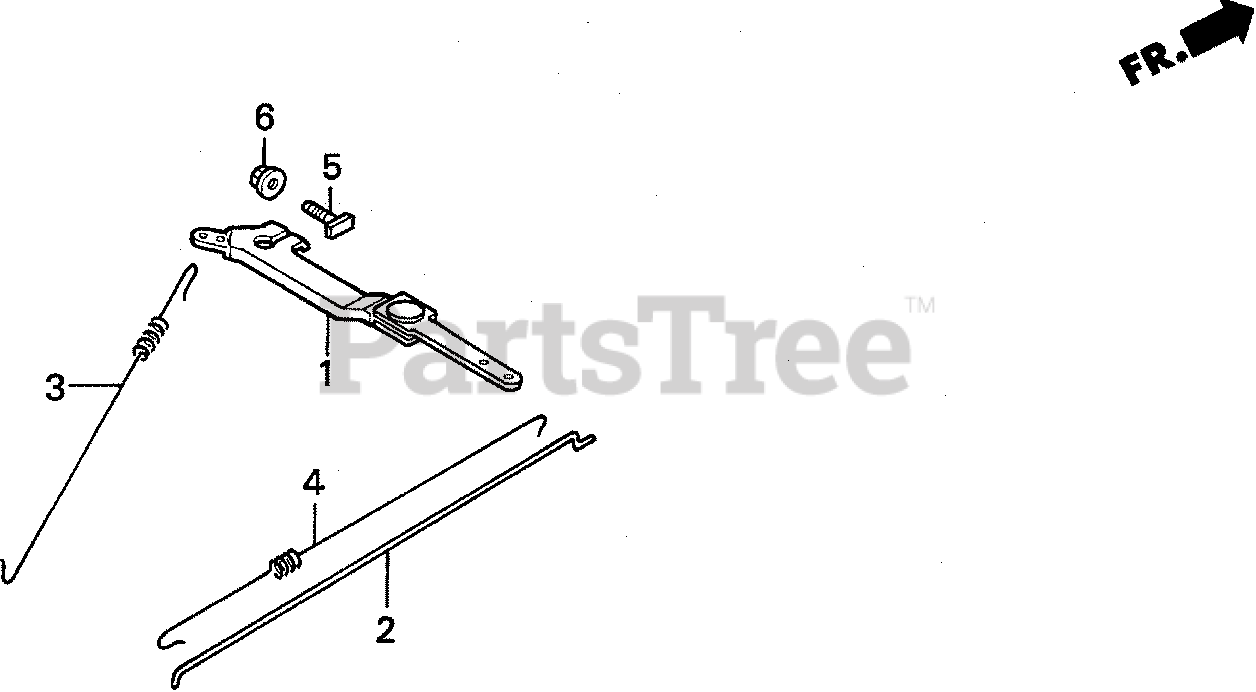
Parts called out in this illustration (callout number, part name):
1	ARM, GOVERNOR
2	ROD, GOVERNOR
3	SPRING, GOVERNOR
4	SPRING, THROTTLE RETURN
5	BOLT, GOVERNOR ARM
6	NUT, FLANGE (6MM)
